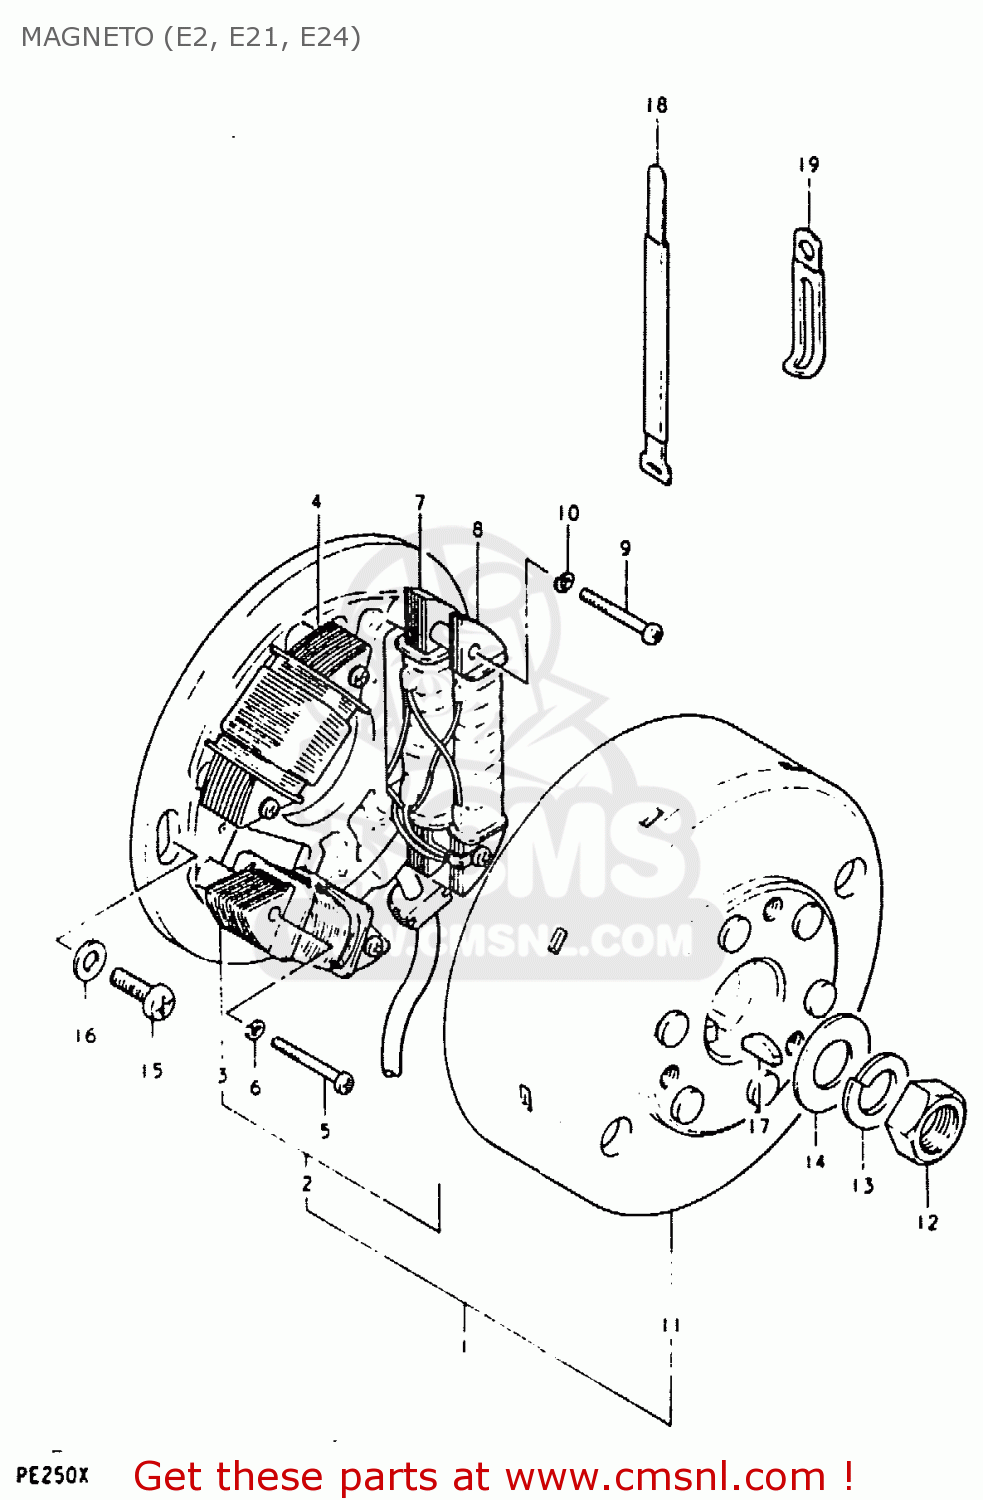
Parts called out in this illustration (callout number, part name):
1	MAGNETO ASSY
2	STATOR ASSY
3	COIL, LIGHTING (A)
4	COIL, LIGHTING (B)
5	SCREW (4X30)
6	LOCK WASHER
7	COIL,PRIMARY
8	COIL,PULSER
9	SCREW
10	LOCK WASHER
11	ROTOR,FLYWHEEL
12	NUT (10MM)
13	LOCK WASHER
14	WASHER
15	SCREW
16	WASHER
17	KEY 4MM
18	CLAMP L:110
19	CLAMP
